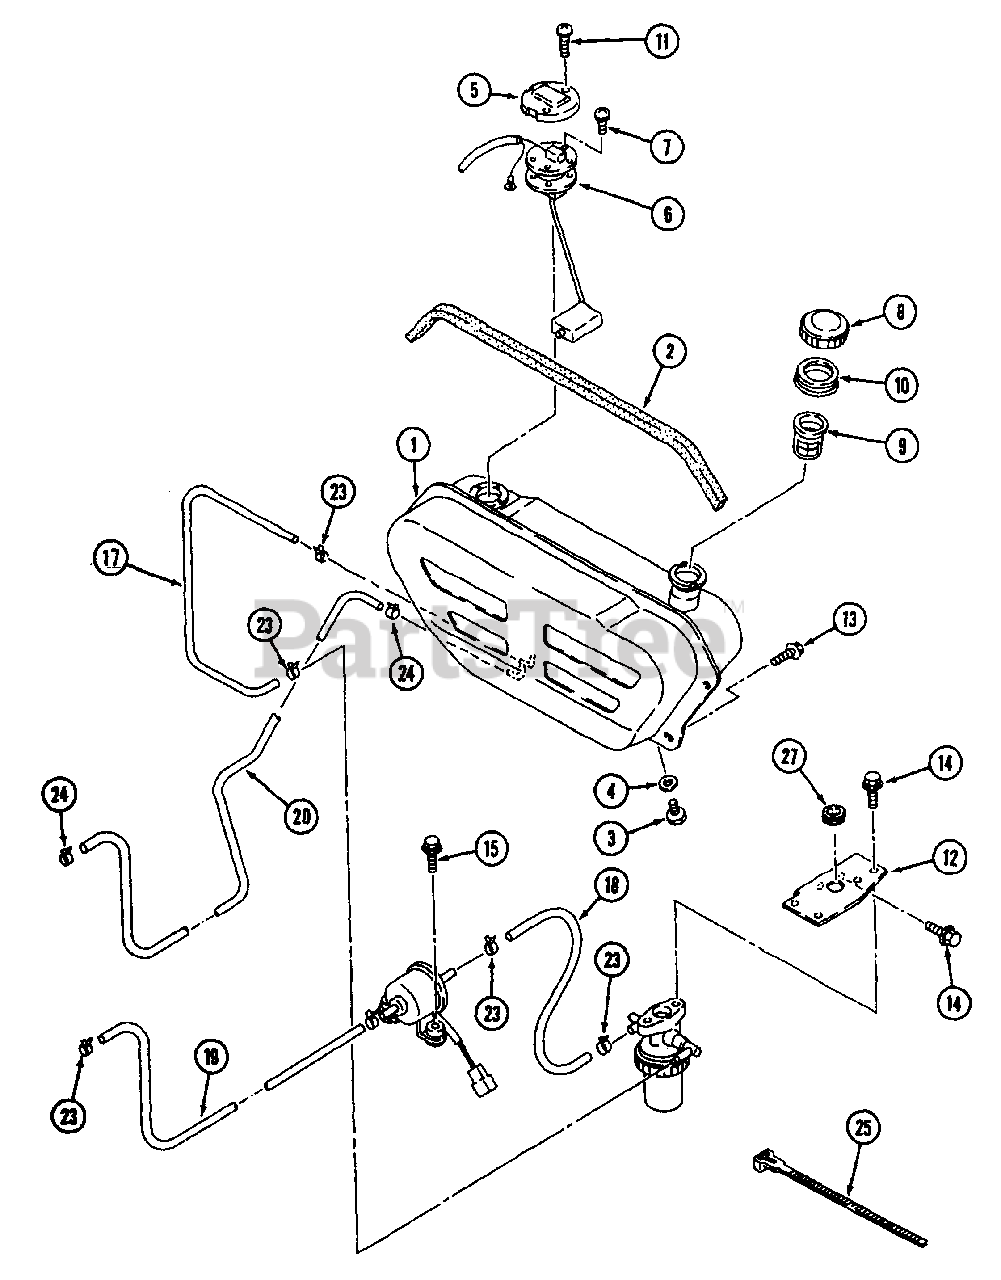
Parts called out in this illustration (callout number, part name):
5	Cover, Fuel Unit
12	Bracket, Filter
15	Bolt
